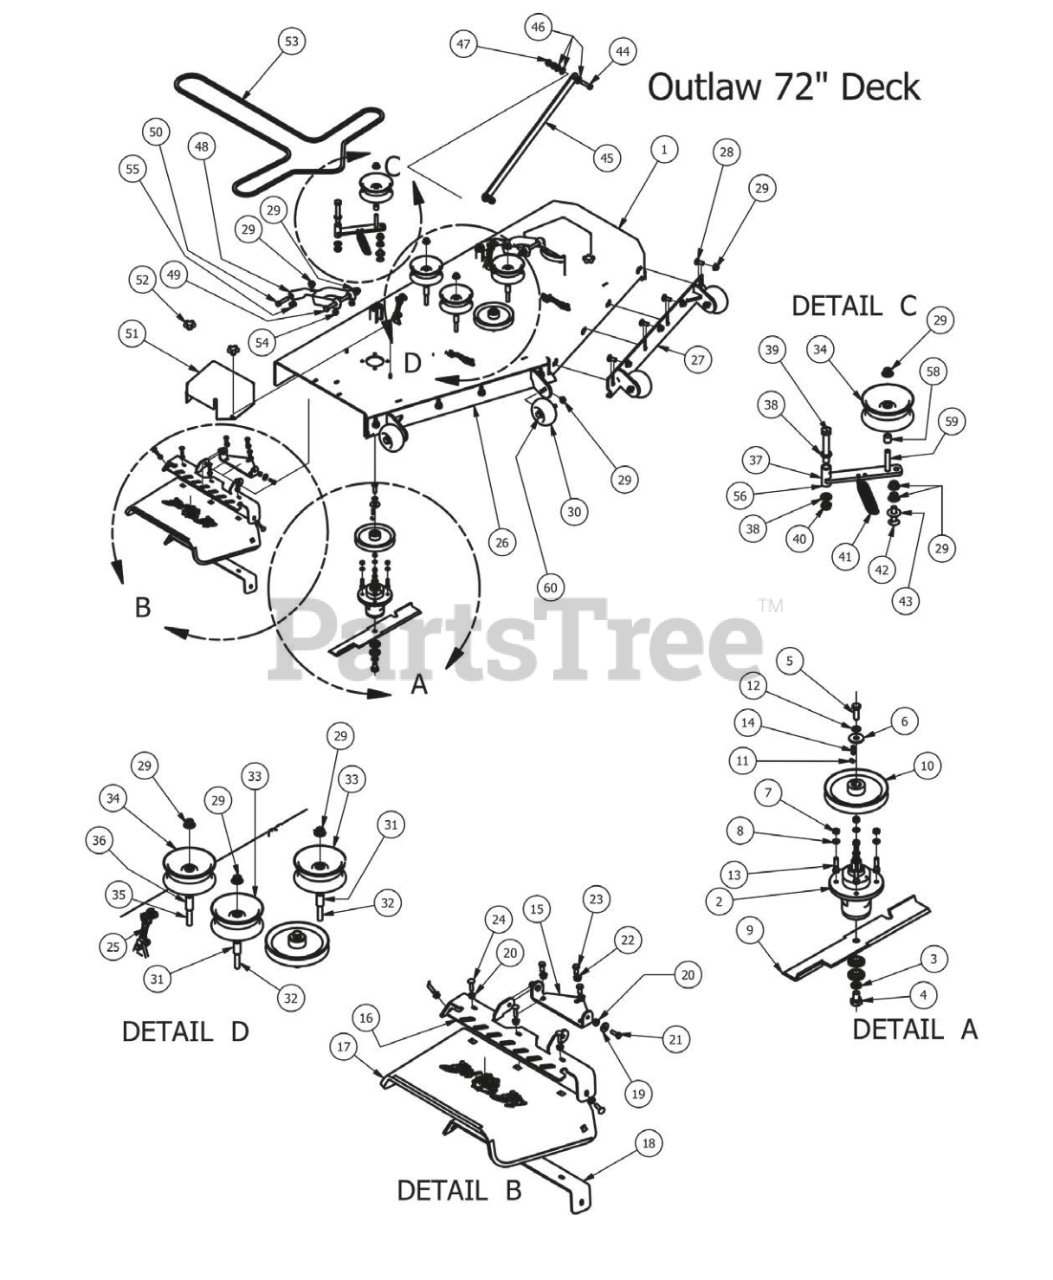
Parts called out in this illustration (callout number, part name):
1	72" Outlaw (Deck Only)
2	Double Bearing Spindle
3	5/8" Lock Washer
4	5/8" x 1 1/2" Grade 8 Bolt
5	1/2"-20 x 1 1/2 - Grade 5 Fine Thread Bolt
6	1/2 Belleville Washer
7	3/8-16 Hex Nuts Zinc
8	3/8 Lockwasher Zinc
9	72" High Lift Fusion Blade
10	7" Deck Pulley
11	3/8" Set Screw
12	1/2" Lock Washer
13	3/8" x 1 1/2" Hex Bolt
14	1/4" x 1" Key
15	Discharge Chute Hanger (deck mounted)
16	60" Upper Discharge Chute
17	Rubber Discharge Chute
18	60" Lower Discharge Chute
19	.360 ID Plastic Washer
20	5/16" Flange Nut Zinc W/Serrations
21	5/16" x 1" Bolt
22	3/8" Flange Nut
23	3/8" x 3/4" Hex Bolt
24	5/16" x 1 1/4" Carriage Bolt
25	2- Link Adjustable Deck Hange
26	72" Deck Adustable Front (Right)
27	72" Deck Adjustable Front (Left)
28	1/2" x 1 1/4 Carriage Bolt
29	1/2-13 Nylon Insert Flange Nut
30	Deck Wheel
31	.502 ID X.75 OD X 1.500 Leng
32	1/2 x 3 1/2 Flange Bolt Grade 8
33	5 3/4" Deck Idler Pulley
34	5 3/4 Flat Idler-32FI-92-008 Pulley
35	1/2" x 4" Bolt (Grade 8)
36	1 3/4" Pulley Spacer
37	Deck Idler Bracket
38	.635 ID Plastic Washer
39	5/8" x 4" Hex Bolt
40	5/8" Nylock (1/2 Jam)
41	2009 Deck/Pump Idler Spring
42	1/2 x 2" Carriage Bolt
43	1/2" Flat Washer
44	1/2-13x2 GR 5 Hex Bolt
45	Panhard Linkage Bar
46	.505 Nylon Spacer
47	1/2" Flange Nut
48	Deck Arm Assembly
49	1/2" x 5 1/2" Bolt
50	1/2-13X 2-1/4 GR Hex Bolts
51	72 Spindle Cover
52	5/16" Knob
53	B202 Belt for 72" Outlaw
54	Flange Bushing For Deck Arm upper
55	Flange for Lower Deck Arm
56	Deck Idler Complete Assembly- Componets 29,34,37,58,59
57	Double Bearing For Spindle
58	3/4 OD x 1/2 ID x 3\4 Length
59	1/2-13 x GR 5 Hex Bolt Zinc
60	Deck Wheel Bolt-2011 Outlaw
